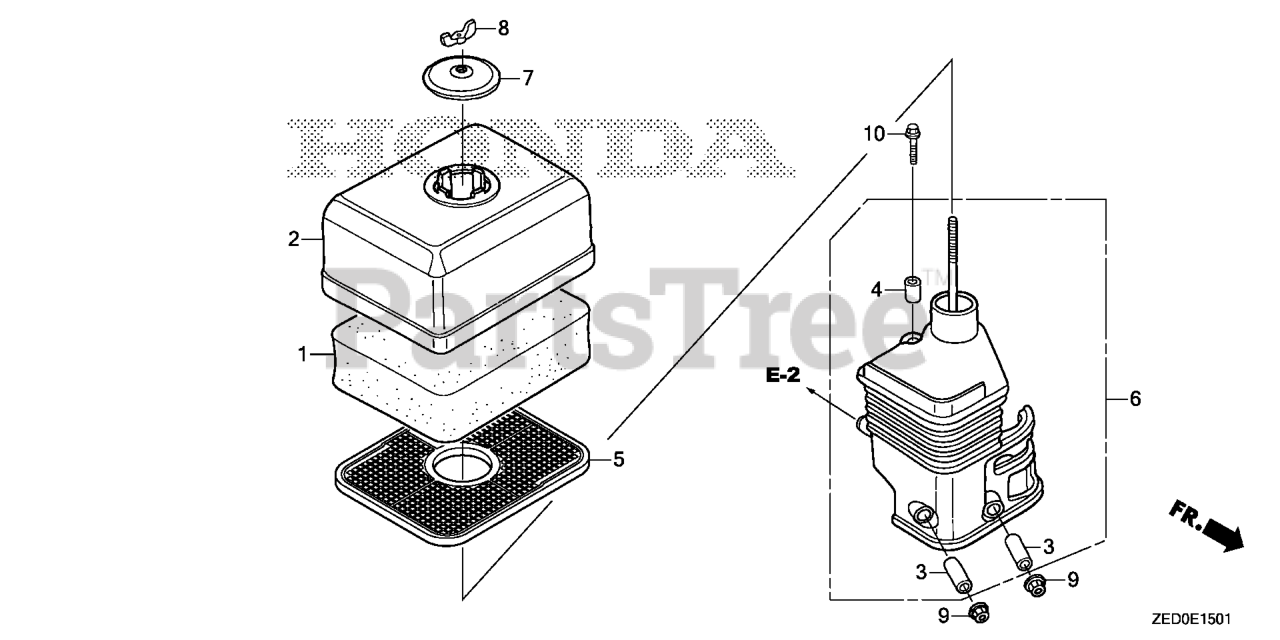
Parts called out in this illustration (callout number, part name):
1	ELEMENT, AIR CLEANER (SEMI-DRY)
2	COVER, AIR CLEANER (SEMI-DRY)
3	COLLAR, AIR CLEANER Use from Engine SN 1786085.
4	COLLAR B, AIR CLEANER
5	GRID, AIR CLEANER
6	ELBOW, AIR CLEANER
7	CAP, CLEANER
8	WINGNUT, TOOL BOX SETTING
9	NUT, FLANGE (6MM)
10	BOLT, FLANGE (6X20)
